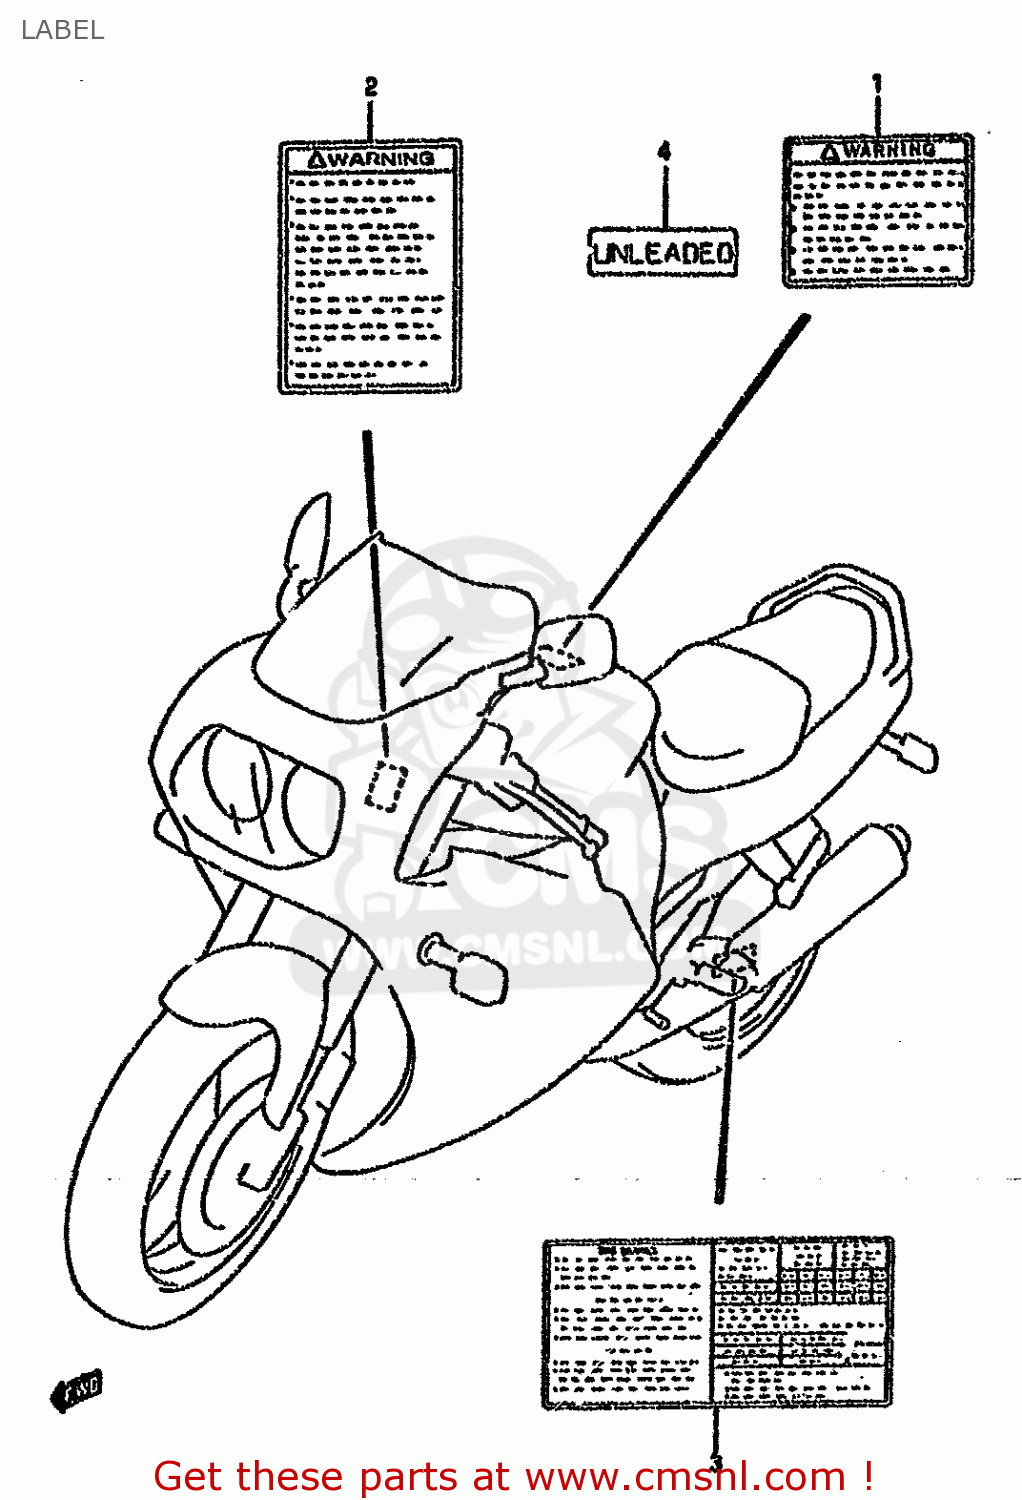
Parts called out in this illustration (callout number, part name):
1	LABEL, WARNING SAFETY
2	LABEL (WARNING SCREEN)
3	LABEL,TIRE AIR PRESSURE
4	LABEL,CAUTION
5	MANUAL,OWNER'S
